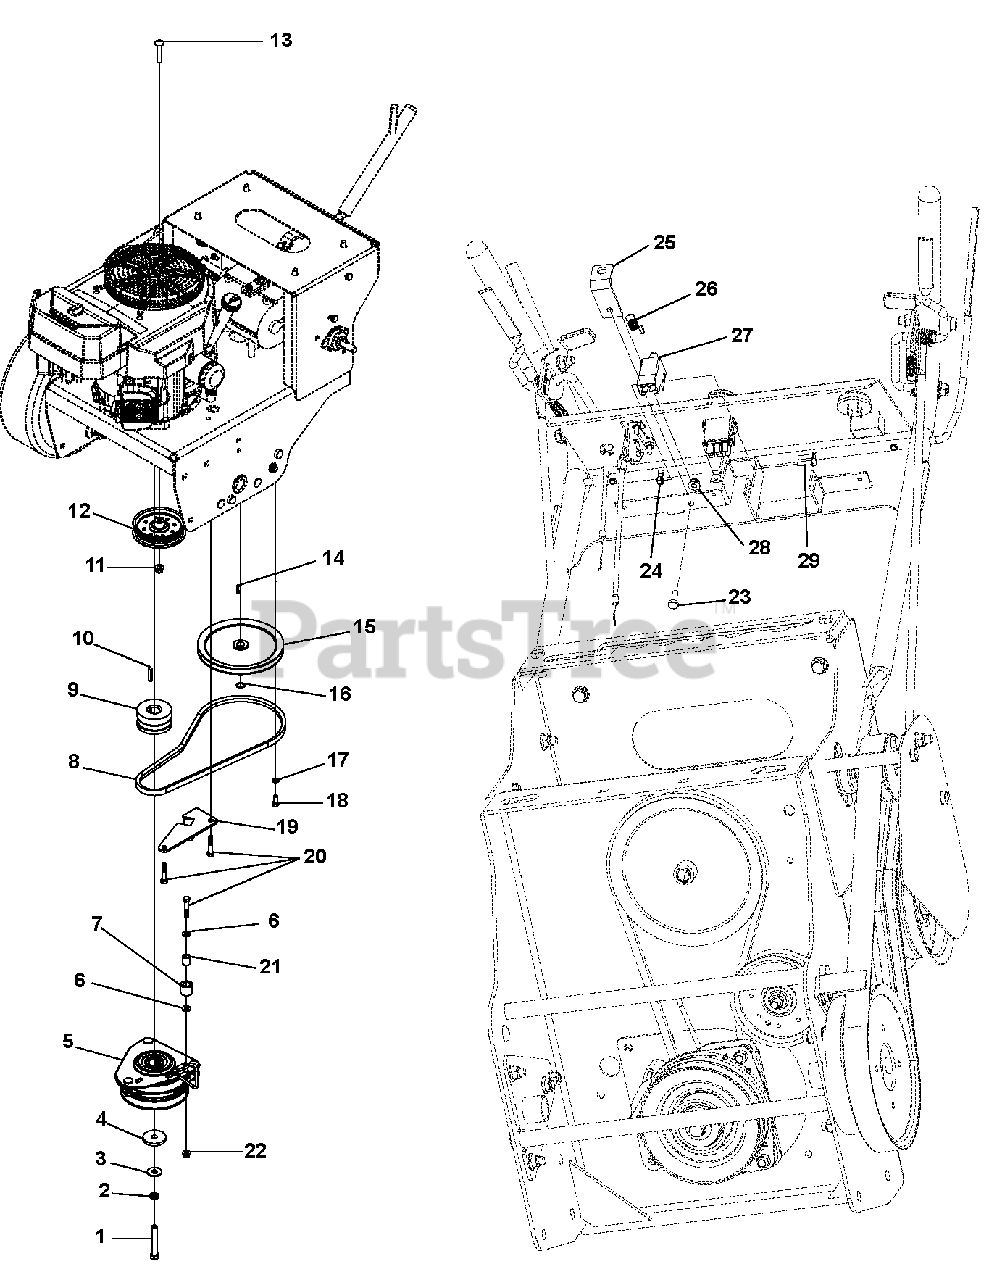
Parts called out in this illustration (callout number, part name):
1	Bolt, .4375-20 x 3.00 Hex 5
2	Washer, .438 Medium Spring Lock
3	Washer, Flat-Steel .50 x 1.25 x .083
4	Washer, Flat-Steel .469 x 2.00 x .25
5	Clutch Assembly, OGURA
6	Washer, Flat-Steel.312 x .734 x .065
7	Bumper, Rubber .62 x 1.0 x .88 LG
8	Belt, HA 40.60 Raw Laminated
9	Sheave,1.002ID x 3.222PIN
10	Key, Square .248 x 1.25 x .248
11	Nut, .38-16 Nyloc Flange
12	Assembly, Idler 4"
13	Bolt, Round Head Square Neck .38-16 x 2.00 SHTPL
14	Key, Woodruff .19 x .75 HRD#9
15	Pulley, V 7.50 x .626
16	Ring, Retaining-External .579 x .035
17	Washer, .313 Medium Spring Lock
18	Bolt, .3125-18 x .750 Hex 5
19	Weldment, Clutch Stop
20	Bolt, .3125-18 x 1.75 Hex 5
21	Bushing, S .407 x .625 x .813 ST
22	Nut, .31-18 Nyloc Flange
23	Bolt, .25-20 x .750 Hex 5
24	Locknut, 10-24 Nyloc
25	Bracket, Brake Link
26	Spring, Tension .047 x .438 x 1.45
27	Switch, Interlock
28	Nut, .25-20 Nyloc Flange
29	Screw, Machine 10-24 x .75 Hex Washer Head
30	Harness, Wire Pro Gear
